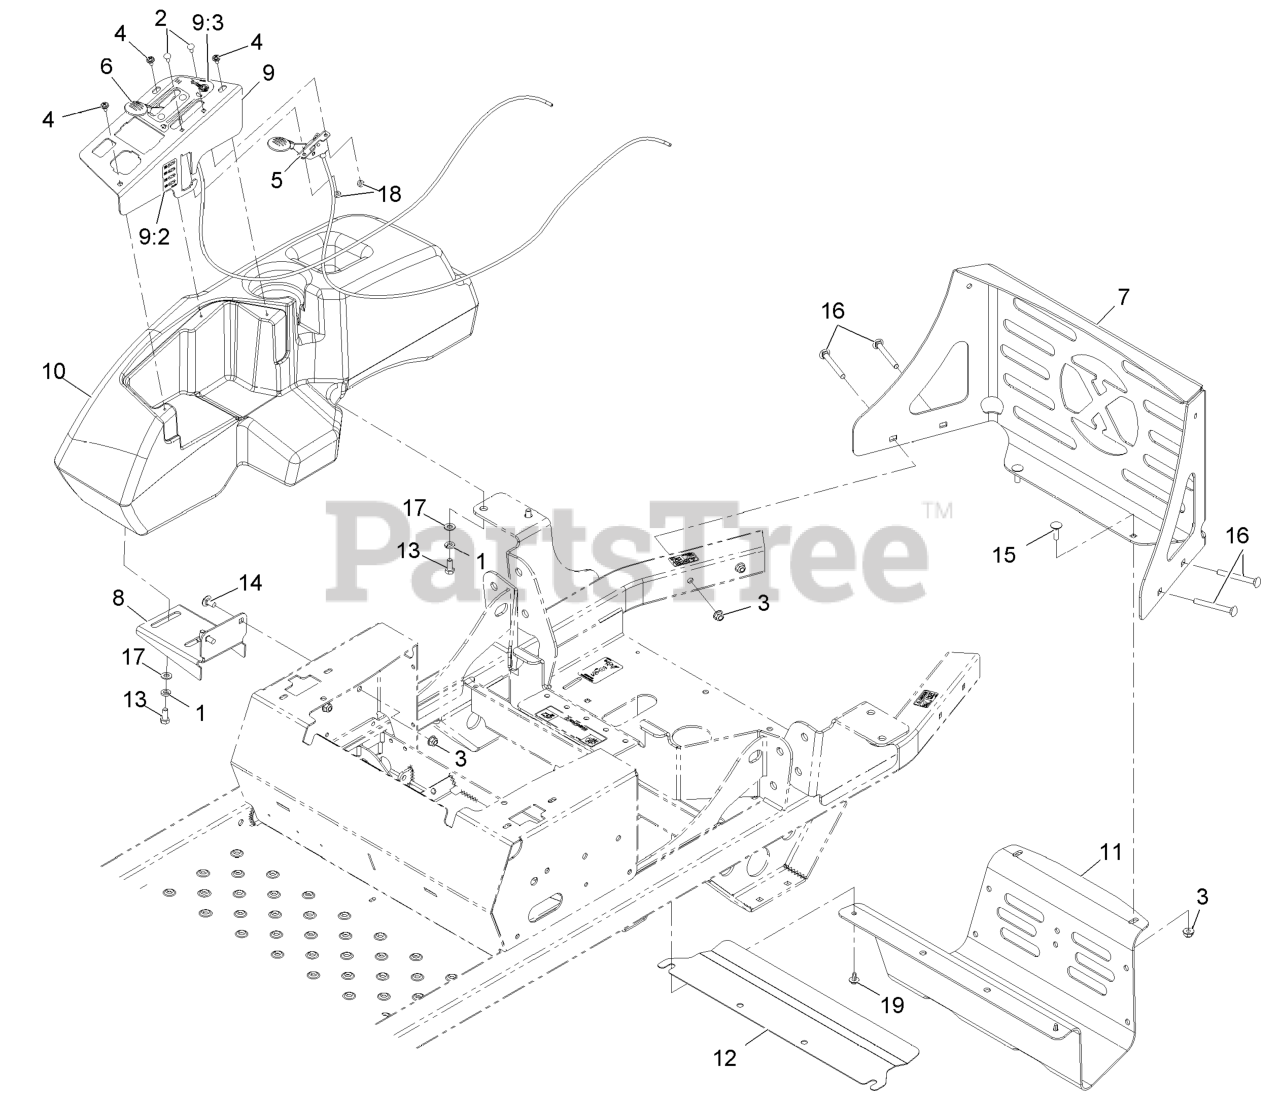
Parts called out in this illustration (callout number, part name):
1	WASHER-LOCK
2	BOLT-CARR
3	NUT-HF, NI
4	SCREW-PPH
5	CONTROL,THROTTLE
6	CONTROL,CHOKE
7	PANEL,REAR GUARD
8	BRACKET-TANK AND FENDER
9	ASM,CONTROL PANEL W/DECAL
9:2	DECAL,FUSE BLOCK
9:3	DECAL-THROTTLE CHOKE
10	CONSOLE,RH
11	GUARD-MUFFLER
13	SCREW-HH
14	SCREW-CARR
15	BOLT-CARR
16	SCREW-CARR
17	WASHER-PLAIN
18	NUT-LOCK, NI
19	SCREW-HHFTF
